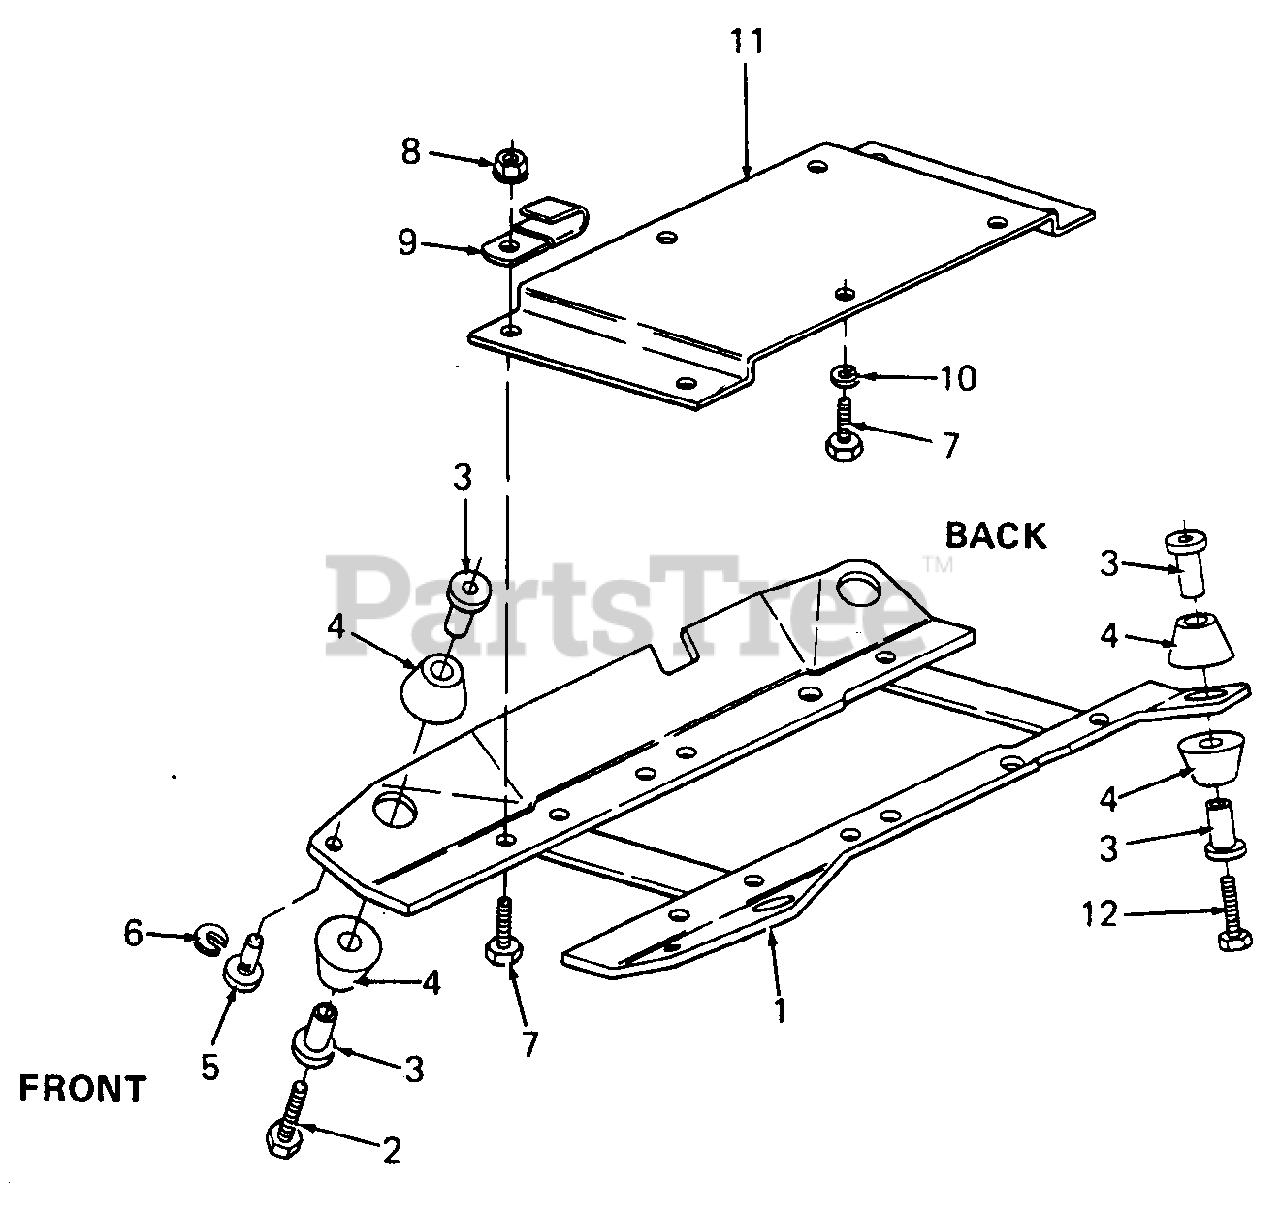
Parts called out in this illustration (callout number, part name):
1	Cradle, Engine Mount
2	Screw, Pan Hd Mach, 3/8-16 X 2.5 Lg GR2
3	Insert, Rubber Mount
4	Mount, Rubber
5	Bumper, Snubbing
6	Shim, Snubbing Mount
7	Screw, Hex Cap, 3/8-16 X 1.0 Lg GR5
8	Nut, Hex Flange Lock
9	Clip, Cable
10	Washer, Lock, 3/8
